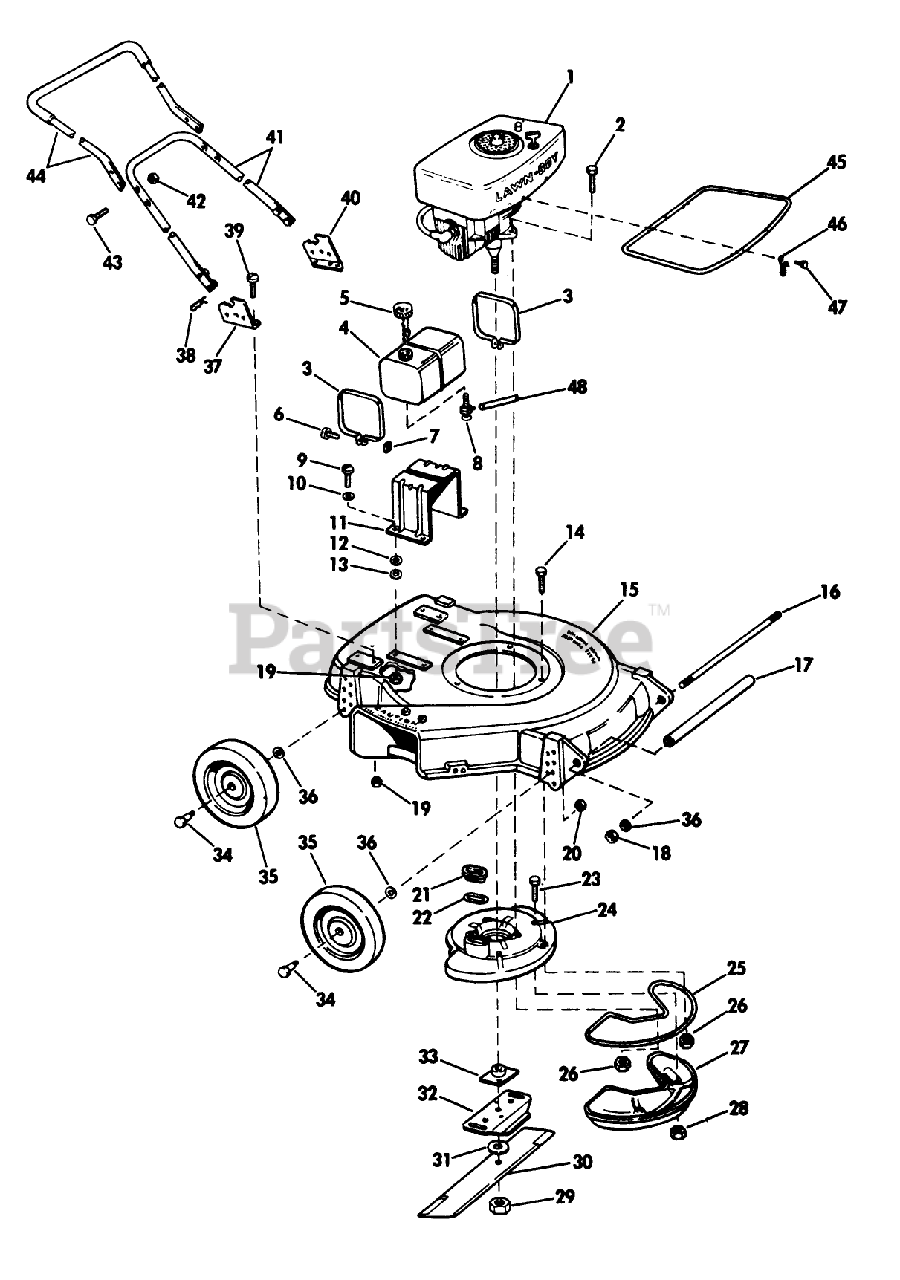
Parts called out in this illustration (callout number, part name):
7	Nut
8	VALVE&SCREEN SM
9	BOLT PIONEER
13	WASHER
14	SCREW
18	LOCKNUT
20	NUT
21	SLEEVE
22	GASKET S
26	NUT
28	LOCKNUT E
29	NUT-BLADE
31	WASHER
33	PLATE AND COLLAR ASM
36	WASHER, LOCK
39	SCREW S
43	SCREW
